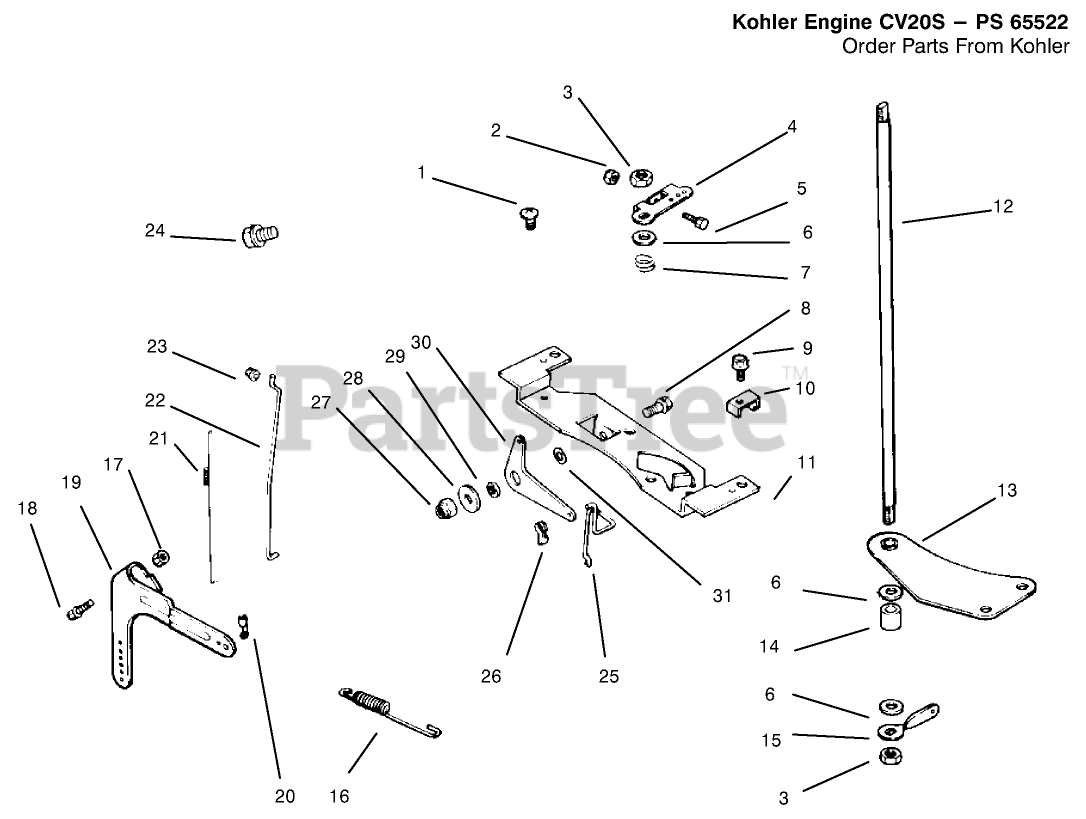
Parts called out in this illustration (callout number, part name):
1	Screw
2	Nut
3	Nut
4	Lever-Throttle Control
5	Screw
6	Washer
7	Spring-Throttle Shaft
8	Screw
9	Screw
10	Clamp
11	Bracket-Control
12	Shaft-Throttle
13	Bracket-Throttle Shaft
14	Spacer
15	Lever-Throttle Control
16	Spring-Governor
17	Nut
18	Screw
19	Lever-Govenor
20	Bushing-Linkage
21	Spring-Linkage
22	Linkage-Throttle
23	Bushing-Linkage
24	Screw
25	Linkage-Choke
26	Bushing-Linkage
27	Nut
28	Washer
29	Spacer
30	Lever-Choke
31	Washer
